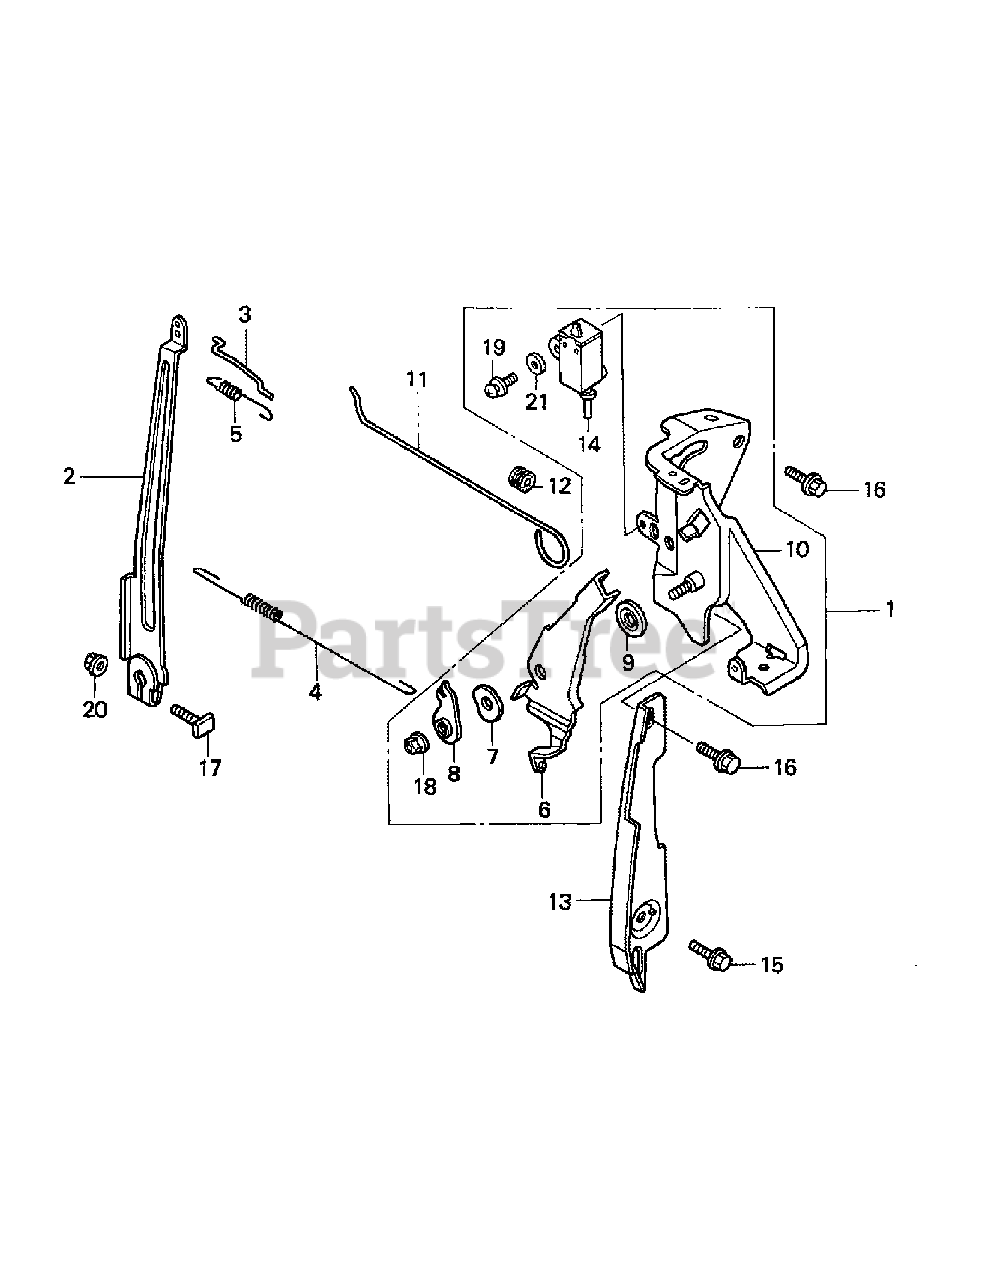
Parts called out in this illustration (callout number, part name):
1	Control Assembly
2	Governor Arm
3	Governor Rod
4	Governor Spring
5	Throttle Return Spring
6	Control Lever
7	Lever Spring
8	Control Lever Washer
9	Control Lever Spacer
10	Control Base
11	Choke Control Rod
12	Choke Rod Grommet
13	Side Plate
14	Engine Stop Switch Assembly
15	Flange Bolt, 6 x 12
16	Flange Bolt, 6 x 14
17	Governor Arm Bolt
18	Self-lock Nut, 6mm
19	Screw-Washer, 4 x 12
20	Flange Nut, 6mm
21	Plain Washer, 4mm
